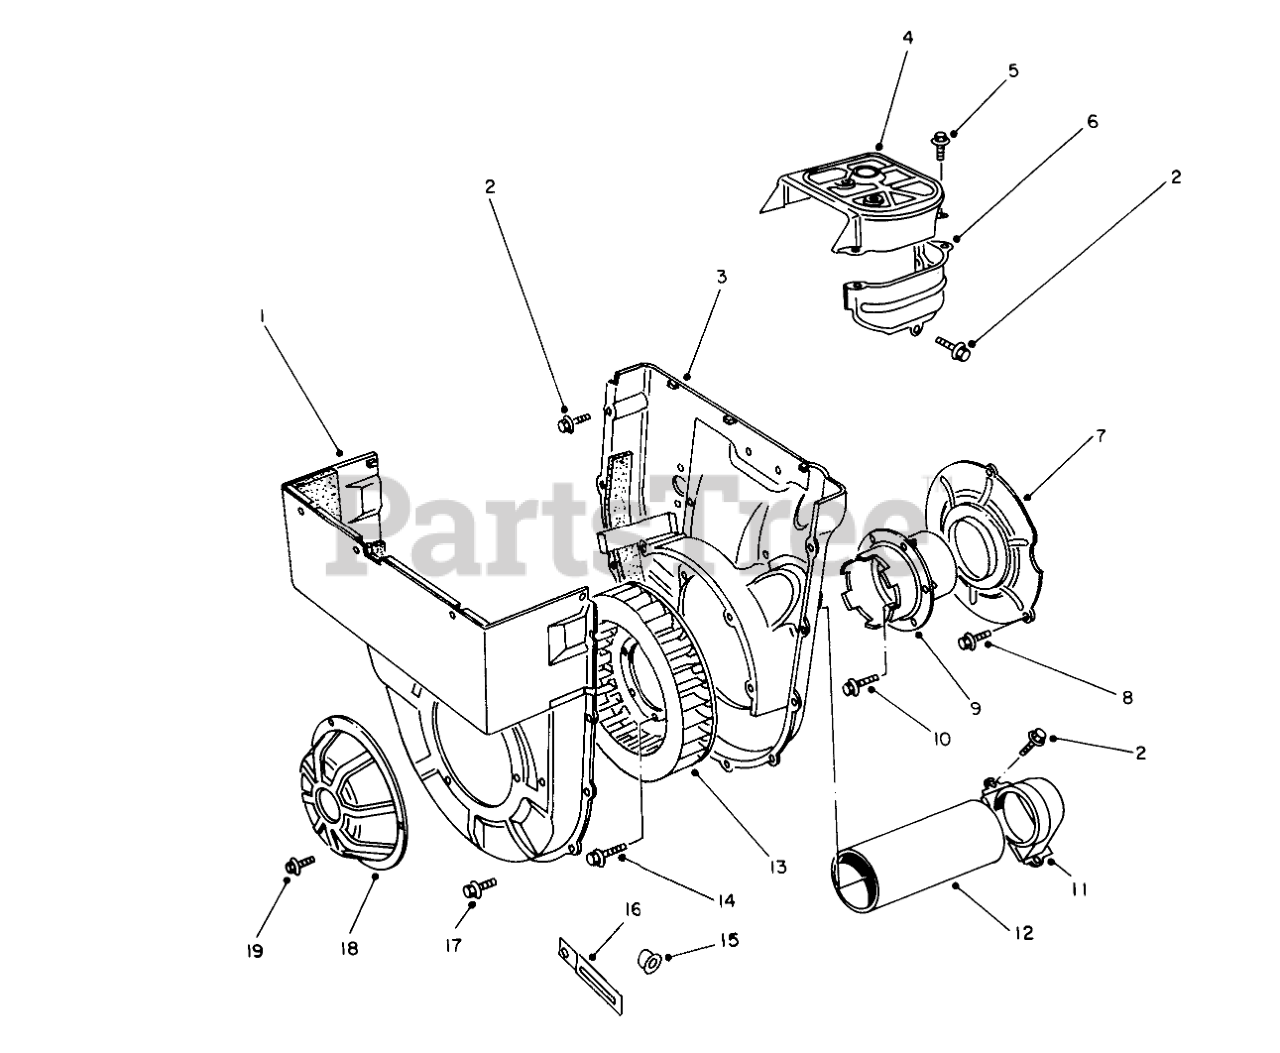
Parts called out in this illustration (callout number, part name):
1	Cover-Outer
3	Cover-Inner
4	Cowling-Upper
6	Cowling-Side
7	Cover-Magneto
9	Pulley
11	Guide-Air Duct
12	Tube-Air Duct
16	Clamp-Air Duct
17	SCREW-HHF
18	Cover
